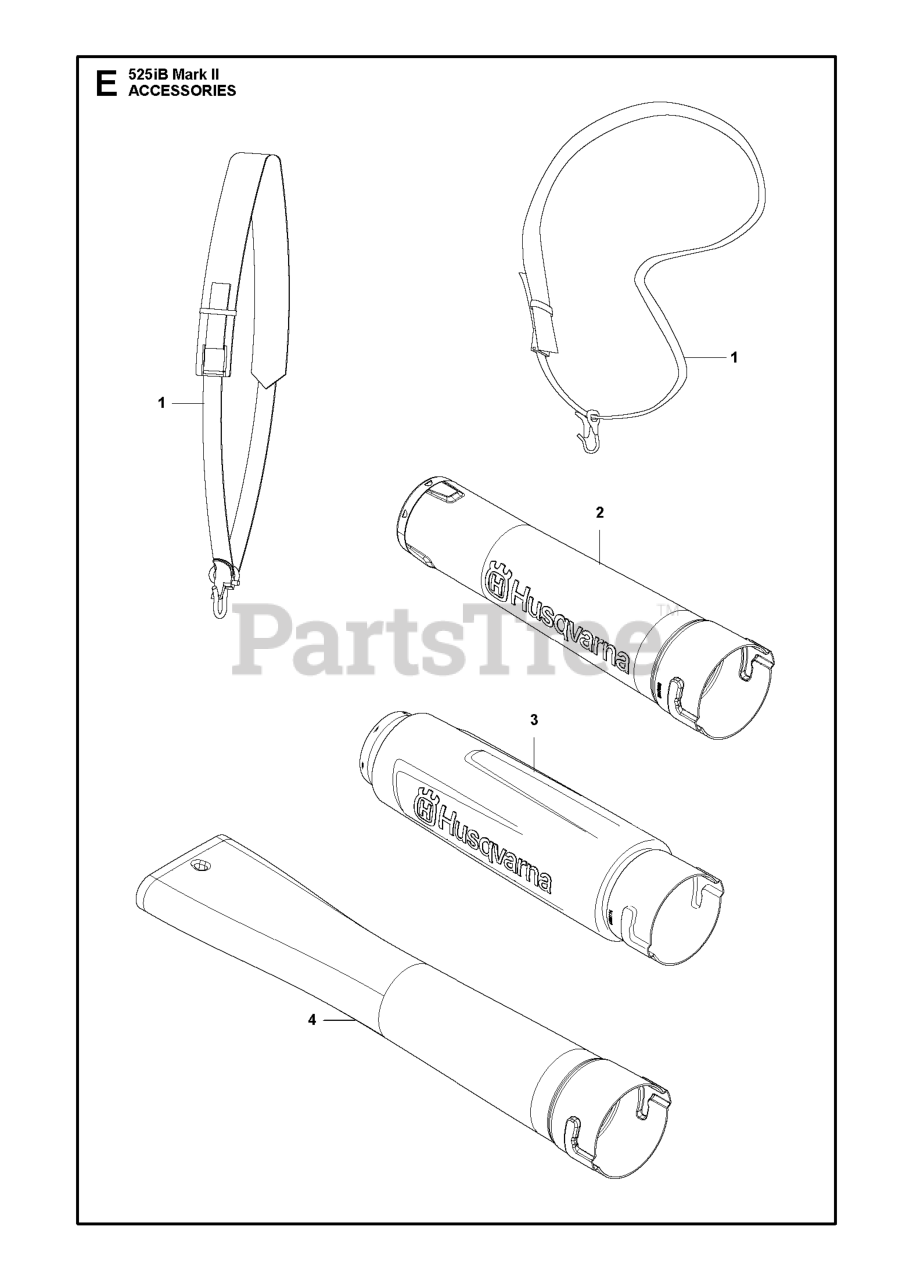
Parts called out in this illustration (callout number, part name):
1	Harness-w/o warning
1	Harness - Diagonal with sign
2	TUBE ASSY NOZZLE 536LIBX
3	TUBE ASSY NOZZLE SILENCER
4	BLOWER NOZZLE FOR 320IB
